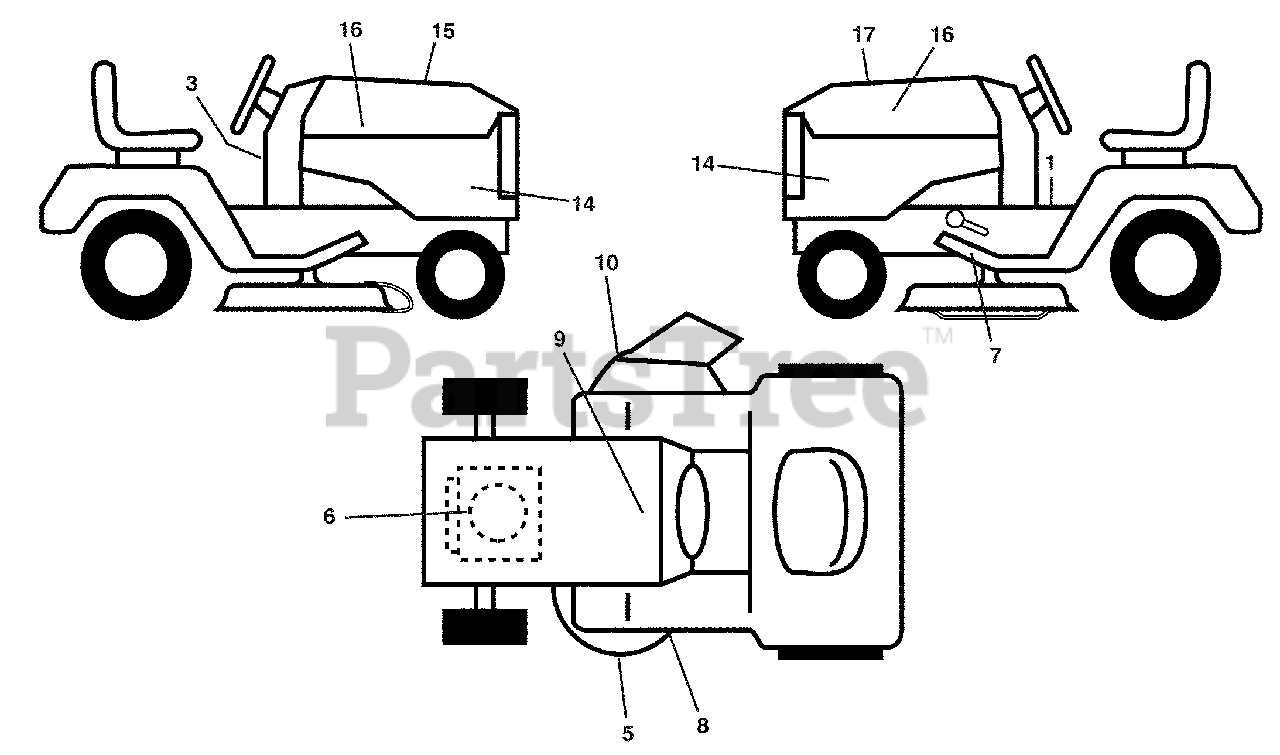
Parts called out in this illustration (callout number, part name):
1	Decal, Warning
3	Decal, Warning Spark Arrestor
5	Decal, Air Induction
6	Decal, Eng. HP
7	Decal, Pedal
8	Decal, Mower Sch.
9	Decal, Battery Dnge/Poi
10	Decal, Warning
14	Decal, Panel Side
15	Decal, Cust. Resp.
16	Decal, Hood Emblem
17	Decal, Replacement
